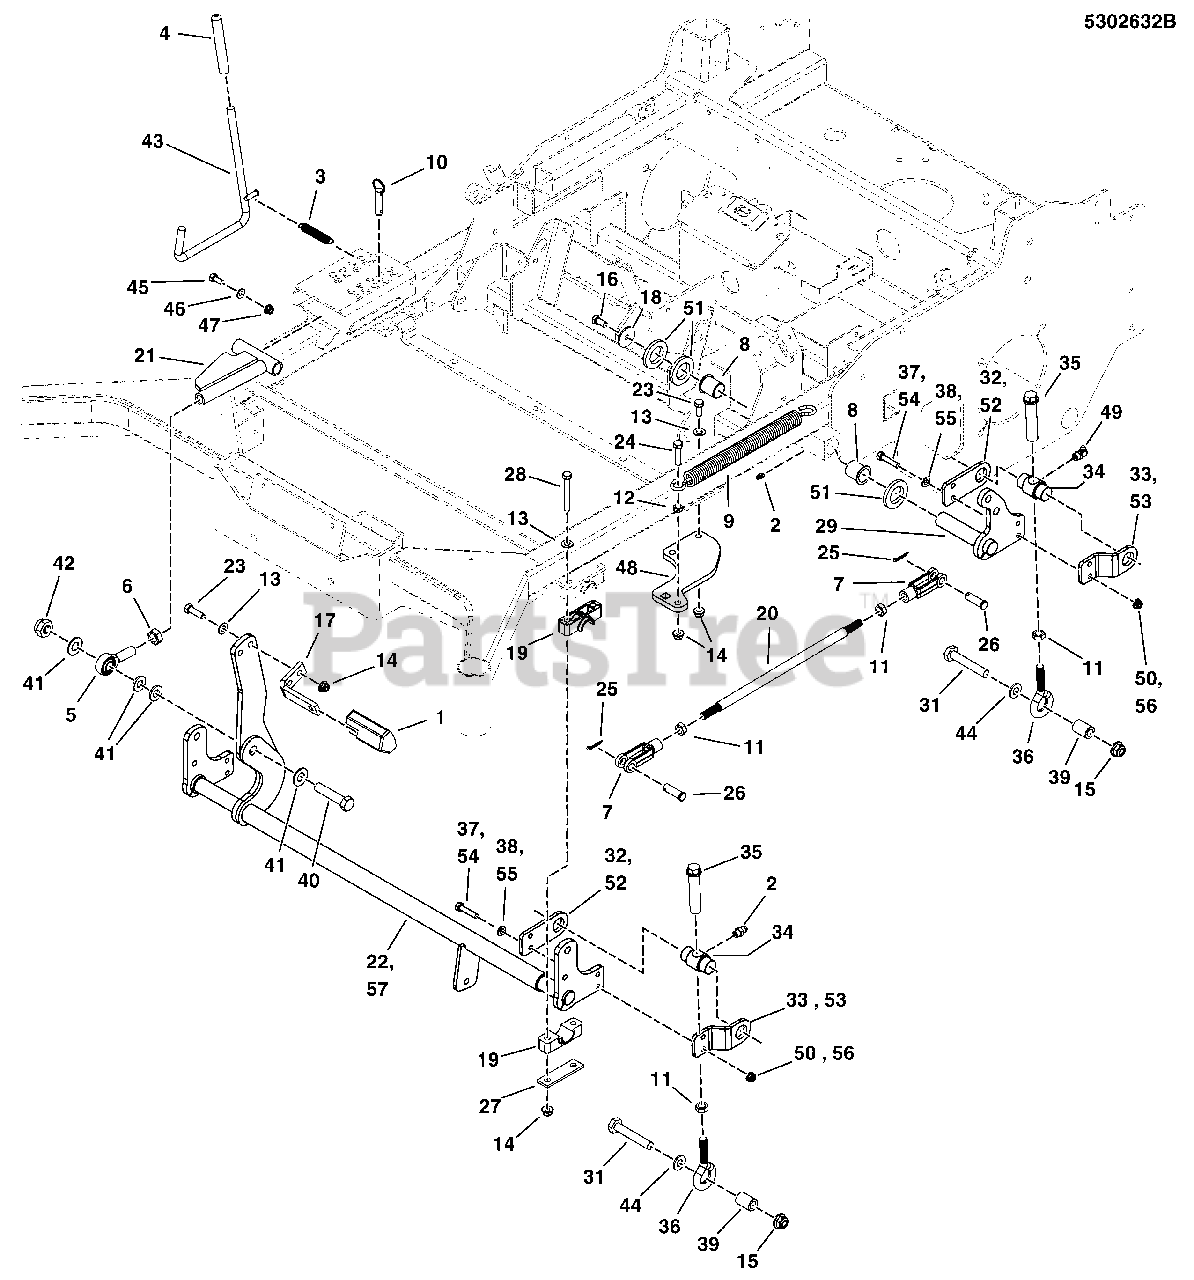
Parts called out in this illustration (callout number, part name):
1	PEDAL, Rubber
2	GREASE FITTING, 1/4-28 STRAIGHT
3	SPRING-EXT, .500 OD X 3.50 LG X .058 WR
4	GRIP, FOAM
5	BALL JOINT, 5/8-18, MALE
6	NUT, 5/8-18, HEX JAM
7	CLEVIS, 1/2-20, STEEL
8	BUSHING, 1.00 X 1.13 X 1.38, PLASTIC
9	SPRING-EXT, 1.393 ODX13.25LGX.218WR, BLK
10	PIN, HITCH, 1/2 X 2.00 OAL, YP
11	NUT, 1/2-20 HEX JAM
12	NUT, 3/8-16 HEX
13	WASHER, 3/8 SAE
14	NUT, 3/8-16 HEX NYLOCK FLANGE
15	NUT, Hex Flange, Nylock, 1/2-13
16	BOLT, 3/8-16 X 3/4, GD5, YZ WITH PATCH
17	PEDAL, FOOT - BLK
18	WASHER, .390 X 1.50 X .109, YZ
19	PIVOT BLOCK, PLASTIC
20	ROD, DECK LIFT, TWR
21	WELD, DECK ADJUSTER LINK - RED
22	WELD, DECK LIFT SHAFT, 200XT-72 - RED
23	BOLT, 3/8-16 X 1-1/4" GD5 CZ
24	BOLT, 3/8-16 X 1-3/4" GD5 CZ
25	PIN, COTTER, 1/8 X 3/4
26	PIN, CLEVIS, 1/2 X 1 1/2, YZP
27	PLATE, PIVOT BLOCK SUPPORT - BLK
28	BOLT, 3/8-16 X 2-3/4" GD5 CZ
29	WELD, DECK LIFT LEVER, S200XT, LH - BLK
31	BOLT, 1/2-13 X 2-3/4 GD5 CZ
32	BRACKET, INNER TRUNION MOUNT - RED
33	BRACKET, OUTER TRUNION MOUNT - RED
34	PIVOT, DECK LIFT TRUNION, GREASABLE
35	ADJUSTER, HEIGHT
36	EYE BOLT, 1/2-20 X 4-1/4, 1 EYE, CZ
37	BOLT, 5/16-18 X 1-1/2 GD5 CZ
38	WASHER, 5/16" SAE
39	SPACER, .52 X .87 X 1.25, CZ
40	BOLT, 5/8-11 X 2-1/2 GD5, CZ
41	WASHER, 5/8 SAE
42	NUT,5/8-11 HEX NYLON LOCK
43	WELD, ROD DECK LIFT - BLK
44	WASHER, 1/2 GD9 YZ
45	BOLT, 5/16-18 X 3/4 GD5
46	WASHER, 5/16" SAE
47	NUT, 5/16-18 HEX NYLOCK FLANGE
48	PLATE, DECK LIFT ASSIST
49	GREASE FITTING, 1/4-28, 90 DEGREE
50	NUT, 5/16-18 HEX NYLOCK FLANGE
51	SHIM, 1.0 X 1.5 X 0.125
52	BRACKET, INNER TRUNION MNT - BLK
53	BRACKET, OUTER TRUNION MNT - BLK
54	BOLT, 3/8-16 X 1-1/2" GD5 CZ
55	WASHER, 3/8 SAE
56	NUT, 3/8 HEX NYLOCK FLANGE
57	WELD, DECK LIFT SHAFT, 200XT-72 - RED
